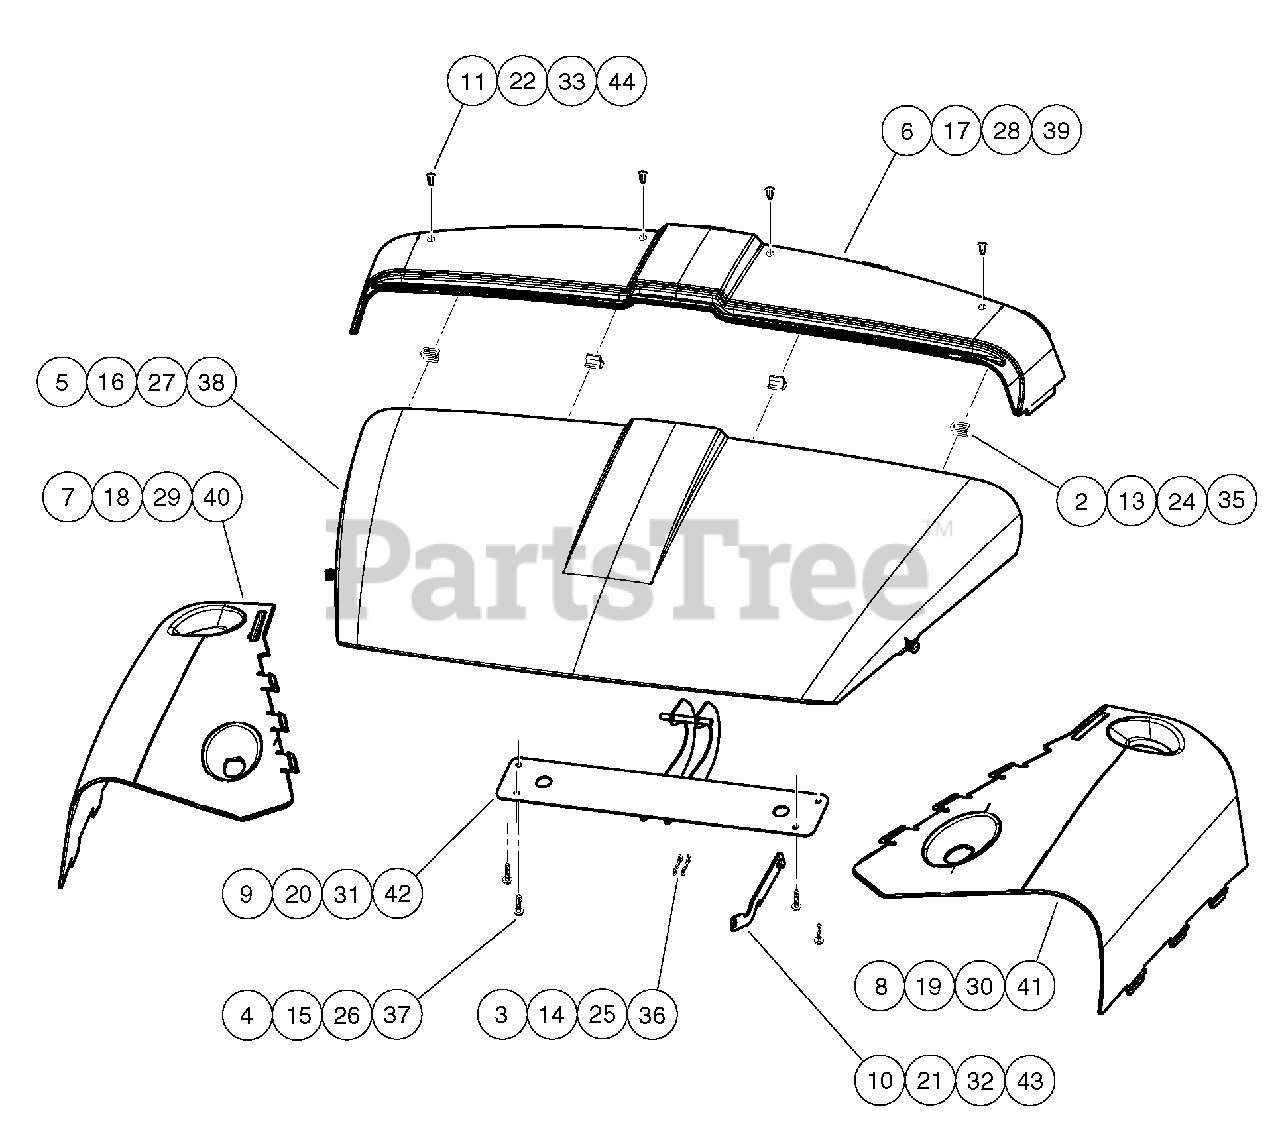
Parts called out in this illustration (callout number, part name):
1	Option, Color, CA, Dark Grn
2	Clip-body-trim
3	Pin, Bow Tie Locking - .072
4	Screw,m6,torx,interlock,thread
5	Hood, Dark Green
6	Panel, Cowl, Center, Dark Green
7	Panel, Cowl, Passenger-Side, Dark Green
8	Panel, Cowl, Driver-Side, Dark Green
9	Weldment, Hinge, Hood
10	Prop, Hood
11	Rivet, Removable, Tuflok 1/4"
12	Option, Color, CA, Dark Gray
13	Clip-body-trim
14	Pin, Bow Tie Locking - .072
15	Screw,m6,torx,interlock,thread
16	Hood, Dark Gray
17	Panel, Cowl, Center, Dark Gray
18	Panel, Cowl, Passenger-Side, Dark Gray
19	Panel, Cowl, Driver-Side, Gray
20	Weldment, Hinge, Hood
21	Prop, Hood
22	Rivet, Removable, Tuflok 1/4"
23	Option, Color, CA, Real Tree Camo
24	Clip-body-trim
25	Pin, Bow Tie Locking - .072
26	Screw,m6,torx,interlock,thread
27	Hood, Real Tree Camo
28	Panel, Cowl, Center, Real Tree Camo
29	Panel, Cowl, Passenger-Side, Real Tree Camo
30	Panel, Cowl, Driver-Side, Real Tree Camo
31	Weldment, Hinge, Hood
32	Prop, Hood
33	Rivet, Removable, Tuflok 1/4"
34	Option, Color, CA, Dlx Real Tree Camo
35	Clip-body-trim
36	Pin, Bow Tie Locking - .072
37	Screw,m6,torx,interlock,thread
38	Hood, Real Tree Camo
39	Panel, Cowl, Center, Real Tree Camo
40	Panel, Cowl, Passenger-Side, Real Tree Camo
41	Panel, Cowl, Driver-Side, Real Tree Camo
42	Weldment, Hinge, Hood
43	Prop, Hood
44	Rivet, Removable, Tuflok 1/4"
